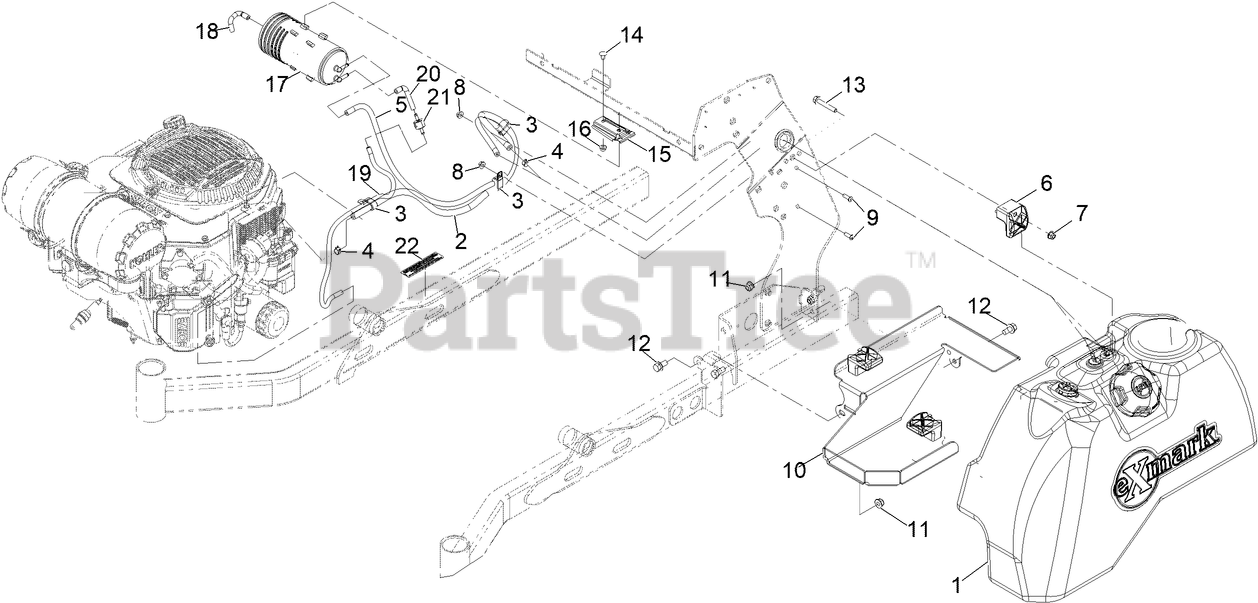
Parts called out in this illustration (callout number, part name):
1	ASM, FUEL TANK 8 GAL
2	HOSE-FUEL
3	CLAMP-R, DOUBLE TUBE
4	CLAMP-HOSE
5	HOSE-FUEL
7	NUT-HF, NI
9	SCREW-HSBH
10	Bracket, Fuel Tank
11	NUT-HF, NI
12	Screw-HH Flg 3/8-16 X 3/4
13	SCREW-HHF
14	SCREW-CARR
15	BRACKET-CANISTER, CARBON
17	CANISTER-CARBON, 800CC
18	HOSE-VENT, FORMED
19	HOSE-VENT
20	HOSE-VENT, FORMED
21	VALVE-CHECK, VACUUM
22	DECAL-ARRESTOR, SPARK
